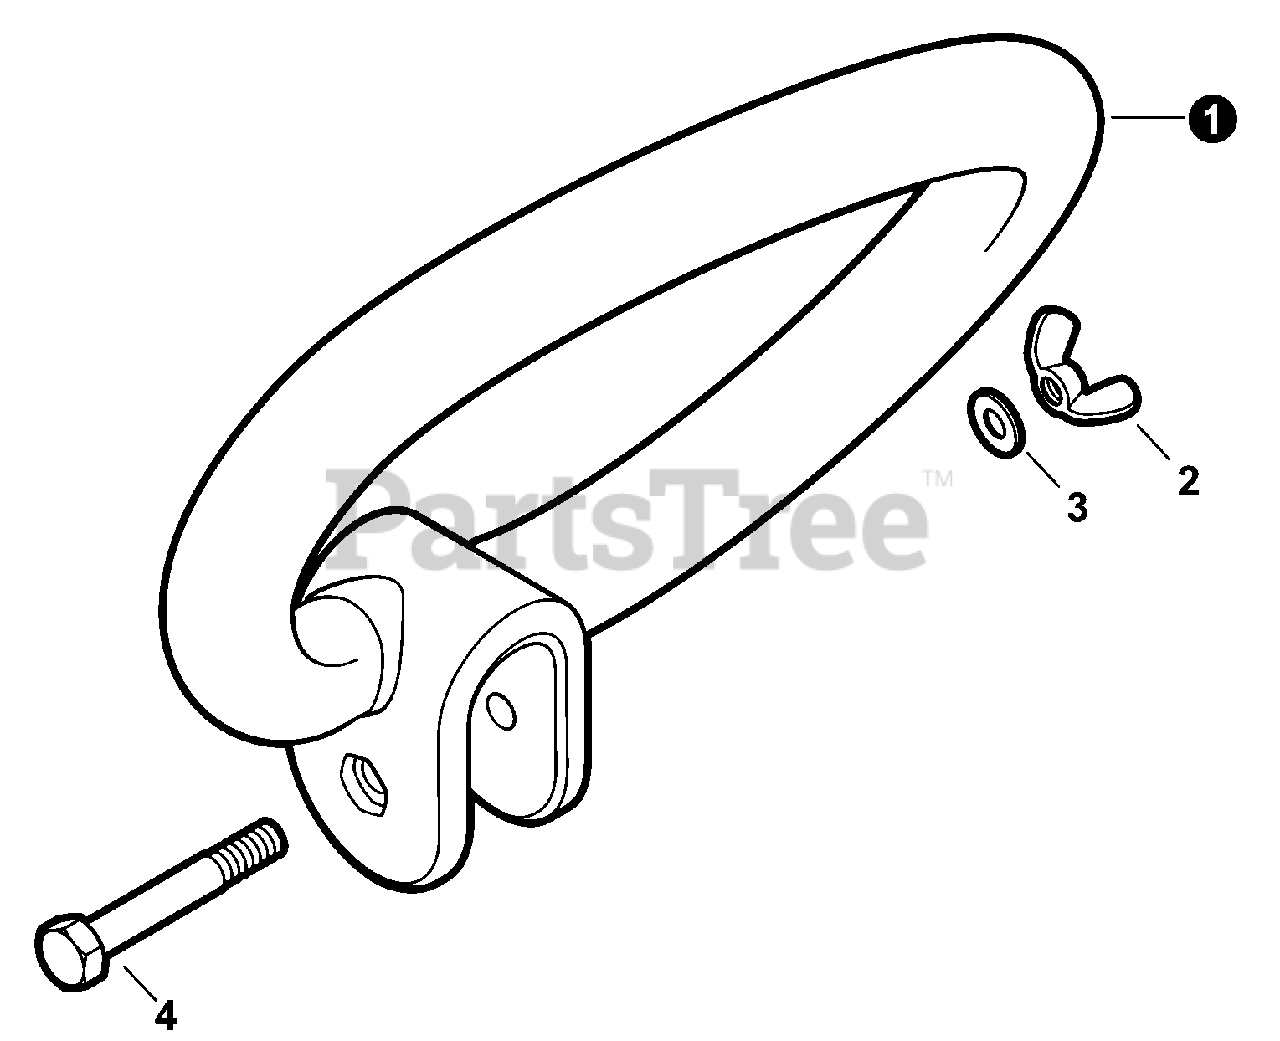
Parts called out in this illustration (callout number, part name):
1	HANDLE, SUPPORT
2	NUT, WING 1/4-20
3	WASHER, 1/4"
4	BOLT 1/4-20×2"
